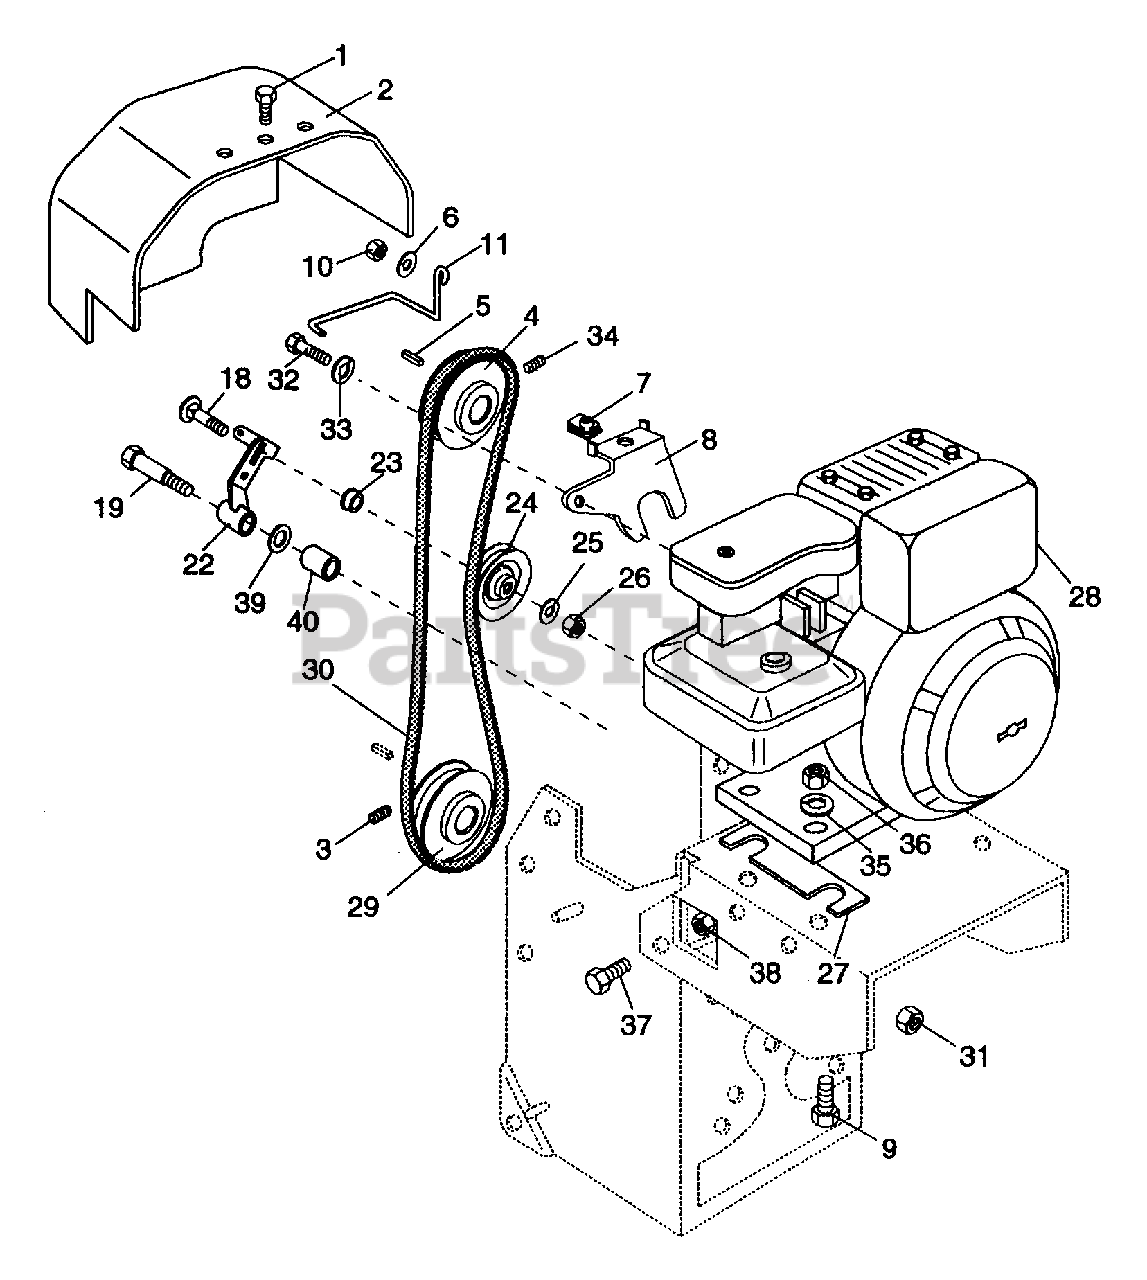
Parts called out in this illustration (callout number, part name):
1	BLT-HEX .25-20X.50 PL GR2
2	BELT COVER
3	SCR-SET .25-20X.38 SKHCUP OH
4	SHEAVE 4.000X.751
5	KEY-SQ .188X1.0X.188 SAE 8630
6	WSHR-FL-STL.281X.62X.065 PL
7	NUT-SPEED U-TYPE .250-20
8	BELT COVER BRACKET
9	BLT-HEX .31-18X1.75 PL GR2
10	NUT-LK-CTR .250-20 PL
11	BELT FINGER
16	KEY-WDRF .125X.625X.250 SAE5
18	BLT-RDHDSQNK .31-18X1.25 SHTPL
19	WHEEL SHOULDER BOLT
22	IDLER ARM FWD
23	SPCR, BRG .315X.50X.688X.281
24	IDLER
25	WSHR-FL-STL .38X.875X.083 PL
26	NUT-LK .312-18 GR A PL
27	SHIM
28	3 HP BRIGGS ENGINE
29	SHEAVE 4.000X.751
30	V-BELT, 4L-WRAPPED
31	NUT-LK-CTR .375-16 GR A PL
32	BLT-HEX .75-16X2.50 PL GR5
33	WSHR-LK .500X.151 HVY PL
35	WSHR-LK .312X.097 PL HVY
36	NUT-HEX .312-18
37	BLT-HEX .38-16X.75 PL GR5
38	NUT-LK TOP .375-16 GR C YWZC
39	WSHR-FL-STL .531X1.062X.095 PL
40	SPACER .513X.748X1.062
